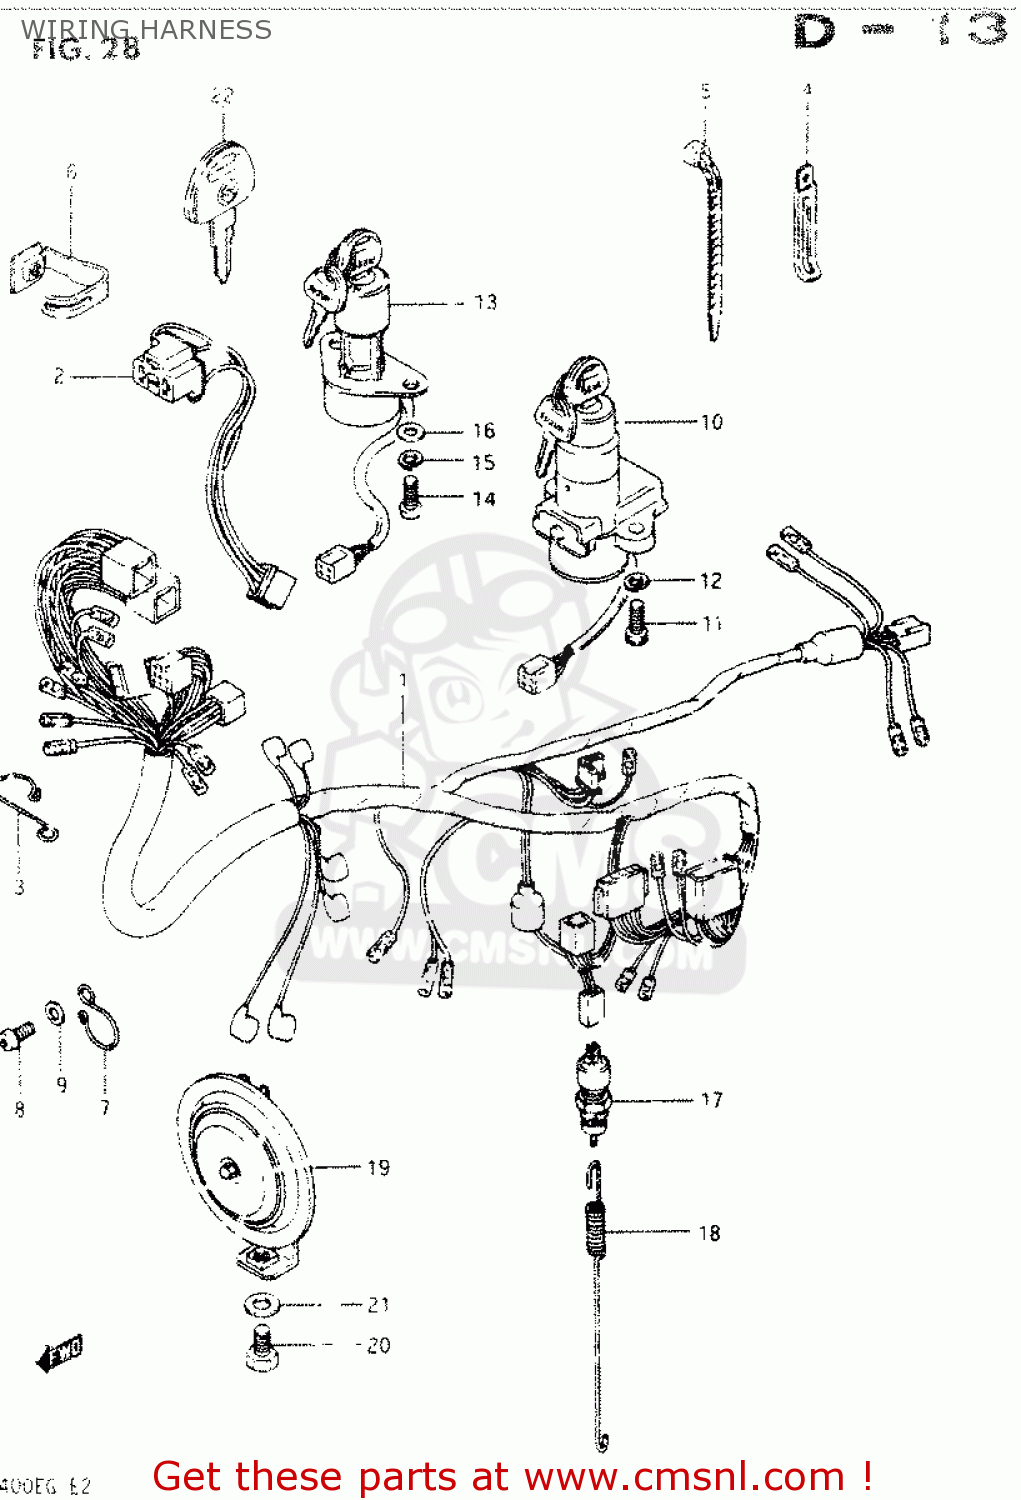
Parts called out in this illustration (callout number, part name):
1	WIRING HARNESS
2	LEAD WIRE,HEADLAMP
3	CLIP,WIRING HARNESS
4	CLAMP
5	CLAMP(L:95)
6	CLAMP,WIRING HARNESS
7	CLIP,WIRING HARNESS
8	SCREW
9	WASHER
10	LOCK ASSEMBLY,STEERING
11	BOLT
12	LOCK WASHER
13	SWITCH ASSY,IGNITION
14	SCREW
15	WASHER,LOCK
16	WASHER
17	SWITCH ASSEMBLY,STOP LAMP
18	SPRING
19	HORN
20	BOLT
21	WASHER
22	KEY,BLANK
